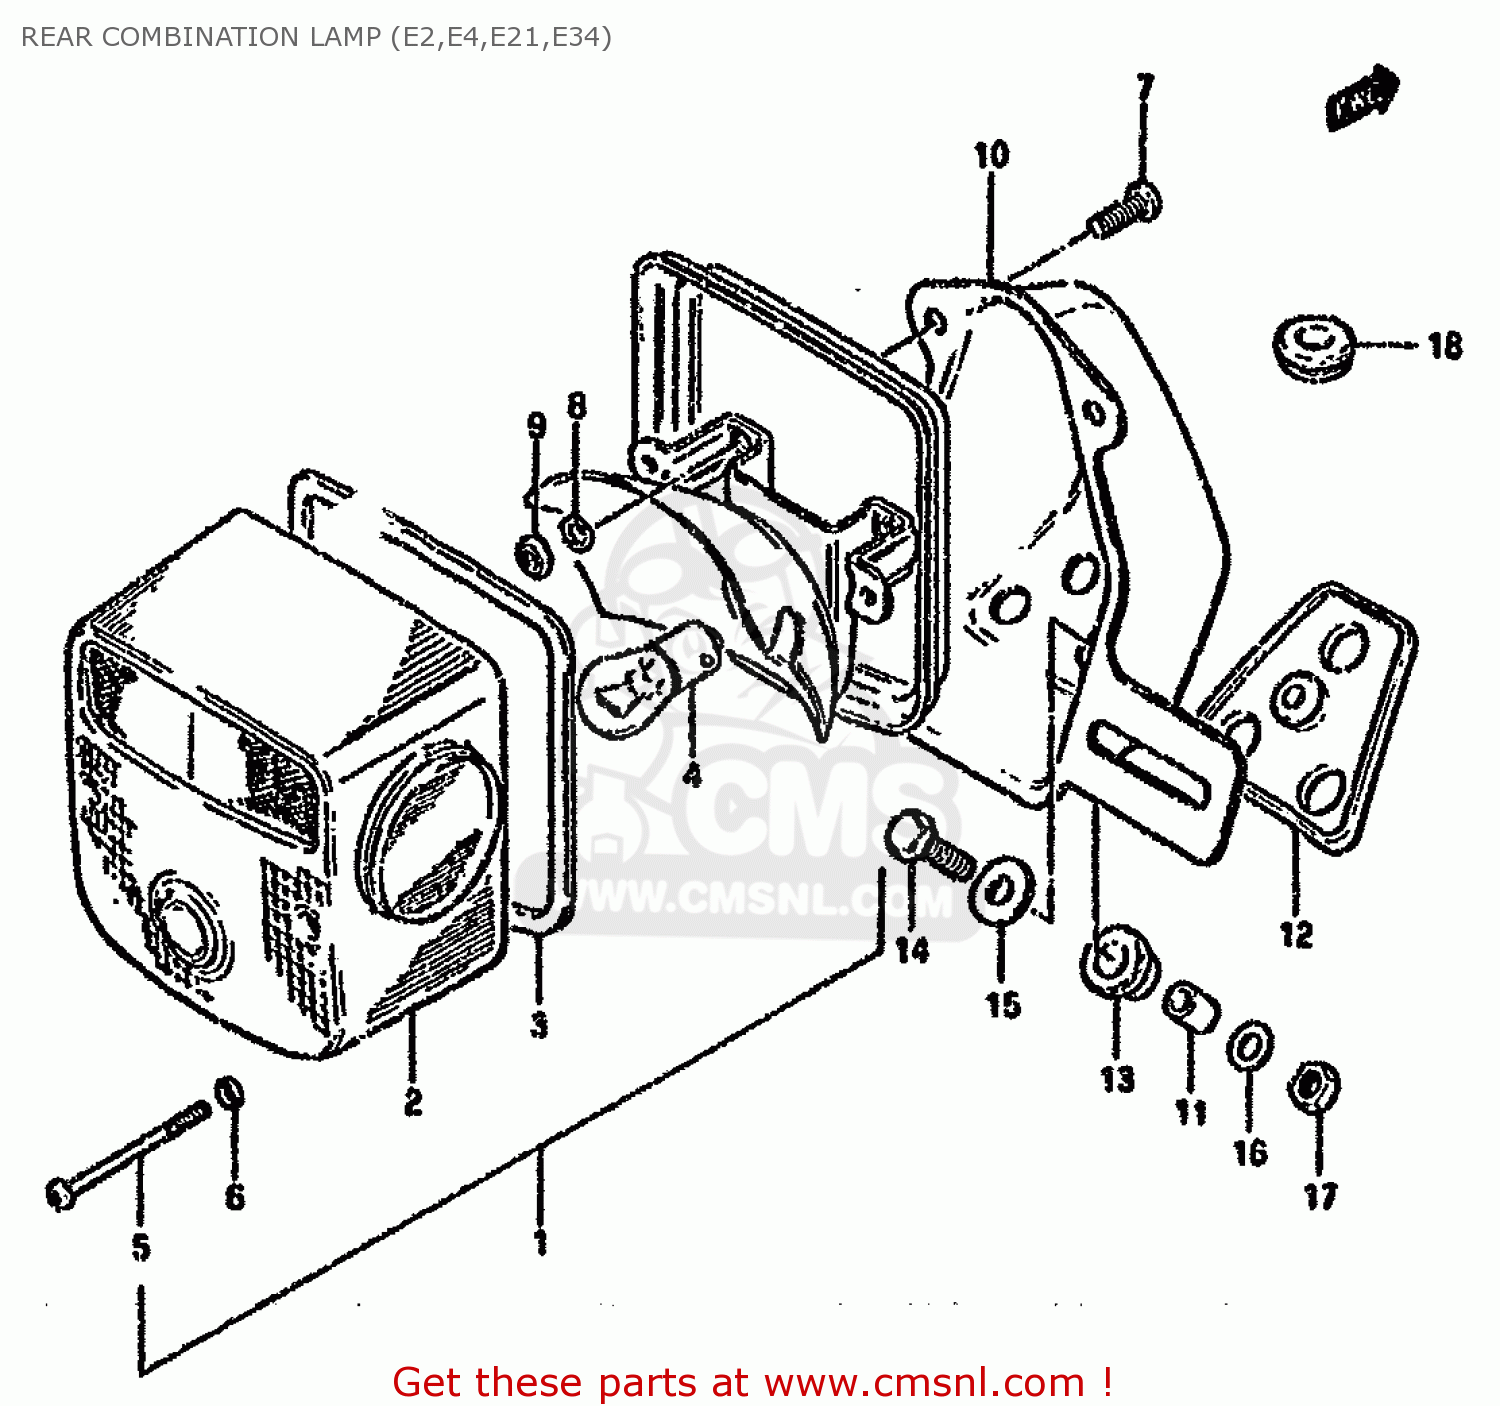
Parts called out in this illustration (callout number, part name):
1	LAMP UNIT,TAIL
2	LENS
3	GASKET (NAS)
4	BULB 12V21/5W
5	SCREW (4X55)
6	GASKET (NAS)
7	SCREW 6X12
8	WASHER,LOCK
9	NUT 6MM
10	BRACKET UNIT,TAIL LAMP
11	SPACER
12	CUSHION
13	CUSHION
14	BOLT
15	WASHER (6.5X20X1.2)
16	WASHER
17	NUT 6MM
18	GROMMET
